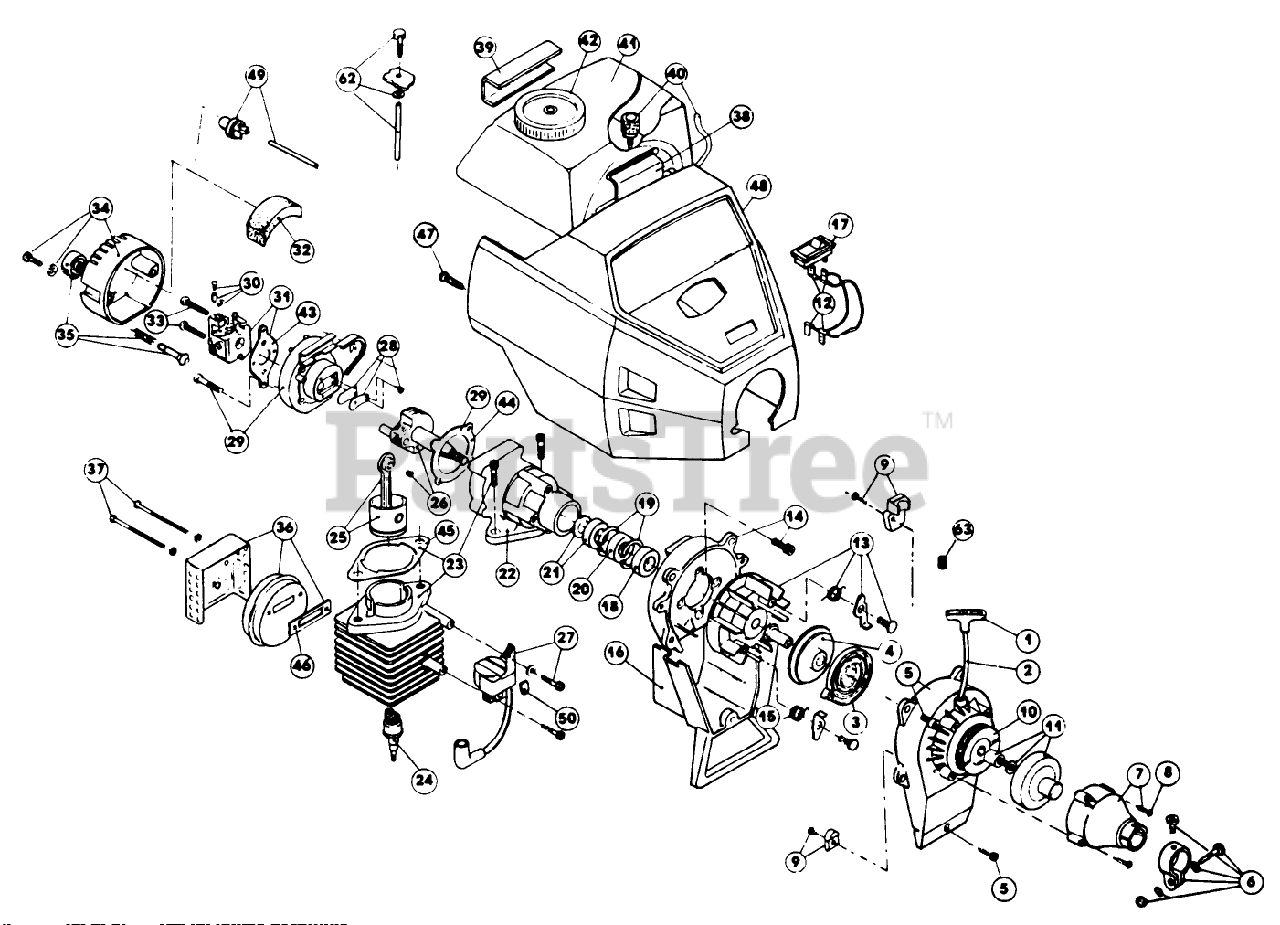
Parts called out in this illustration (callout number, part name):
3	RECOIL SPRING
6	CLAMP ASM - UPPER
14	SHROUD ASM
18	OUTER BEARING
20	SEAL
21	INNER BEARING ASM
24	SPARK PLUG
30	THROTTLE ADJ ASM
37	MUFFLER MOUNTING BOLTS
38	FRONT MOUNTING PAD
39	REAR MOUNTING PAD
40	FUEL LINE ASM
41	Fuel tank
43	CARB.GASKET
49	Primer bulb and hose assembly
57	FLYWHEEL KEY (10-PK)
62	FUEL RETURN LINE ASM
